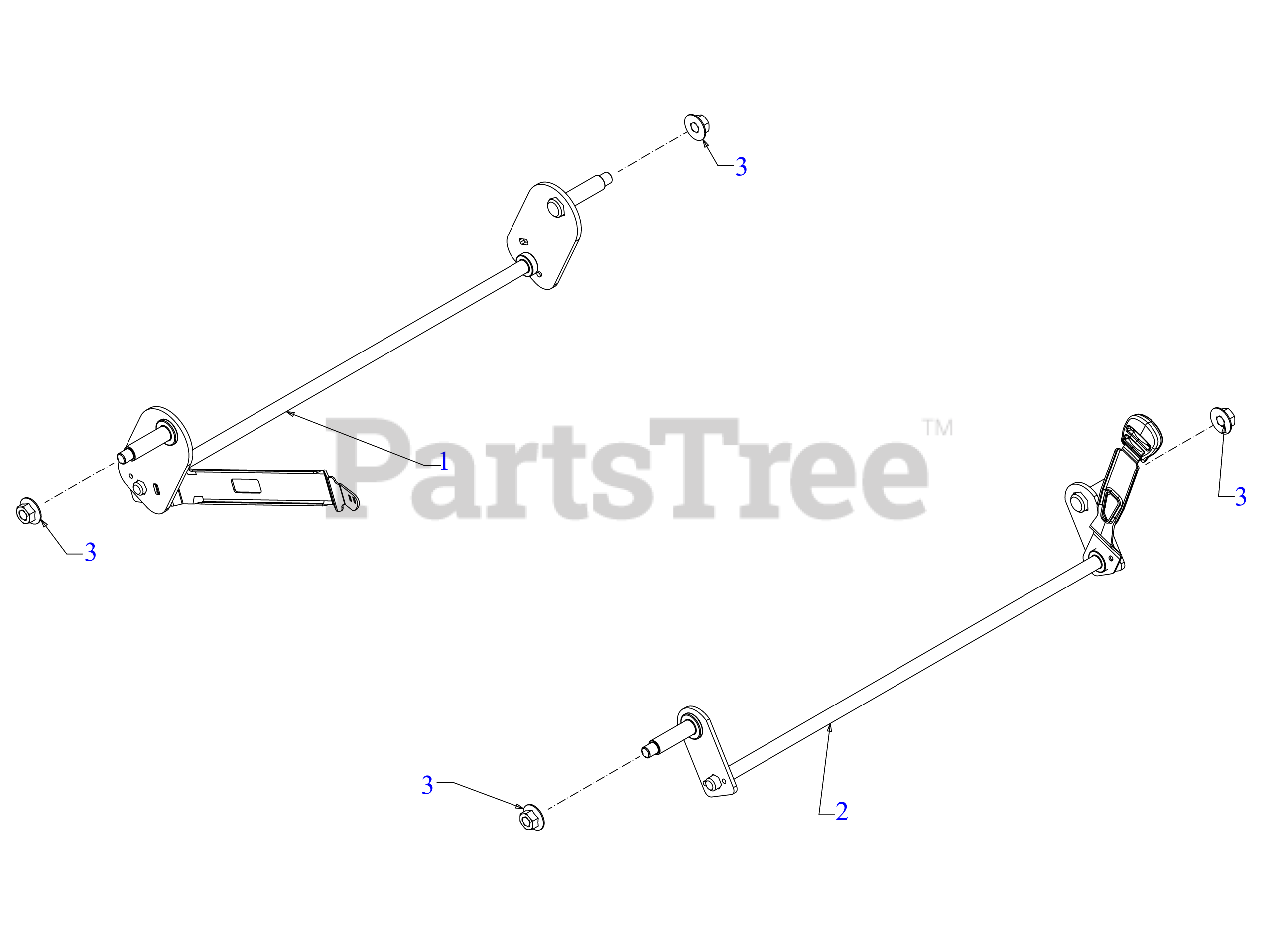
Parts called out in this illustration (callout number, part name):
1	11" REAR AXLE ASSEMBLY
2	FRONT AXLE ASSEMBLY
3	FLANGE LOCK NUT
